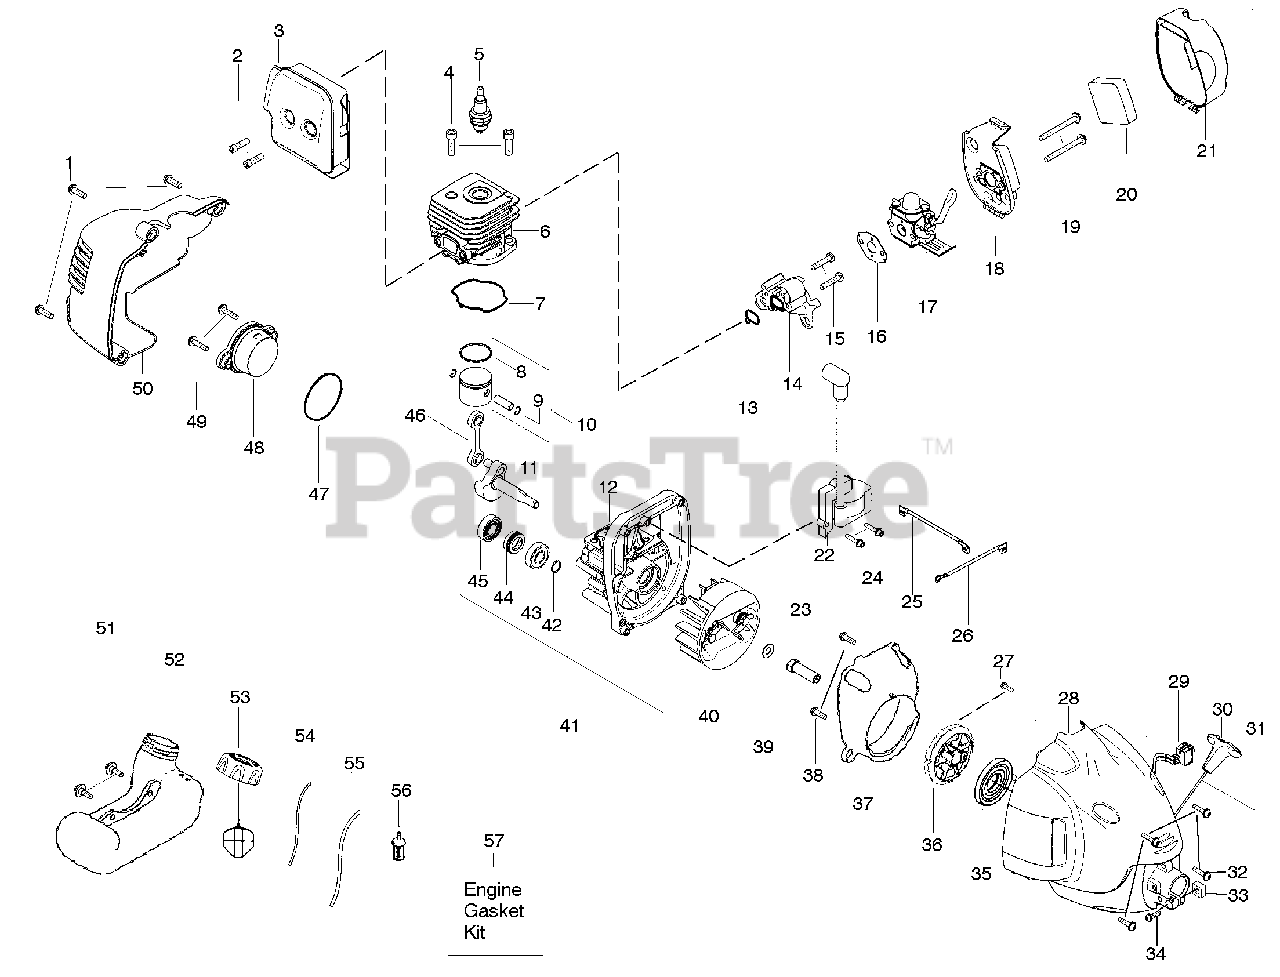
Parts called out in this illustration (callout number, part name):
3	Assy-Muffler/Shield
4	Screw-Cylinder
5	Spark Plug (RCJ 6Y)
7	Seal-Cylinder (kit)
8	Piston Ring
9	Retainer-Piston Pin
10	Kit - Piston
11	Assy-Crankshaft
12	Assy-Crankcase
13	Seal-Cyl/Carb.(kit)
14	Adapter-Carb.
16	Gasket-Carb. (kit)
17	Kit-Carb. Zama (C1U-W18)
17	Kit-Carb. Walbro ( WT-669)
20	Foam-Air Filter
21	Cover-Air Box
22	Ignition Module
23	Coupling-Drive
25	Assy-Leadwire
26	Assy-Ground Wire
28	Assy.-Fan Hsg
30	Handle-Starter
32	Screw
35	Spring-Starter
36	Kit-Starter Pulley
37	Baffle
40	Assy-Flywheel
41	Assy-C'case & C'shaft
42	Retain. Ring-C'shaft
43	Outer Bearing
45	Inner Bearing
46	Kit-Conn. Rod Assy
47	O-Ring-C'case (kit)
48	Assy-Plug
51	Retainer-Tank
52	Assy-Fuel Tank
53	Assy-Fuel Cap
54	Kit-Fuel Line (Small)
55	Kit-Fuel Line (Large)
56	Assy-Fuel Pickup
57	Kit-Engine Gasket
